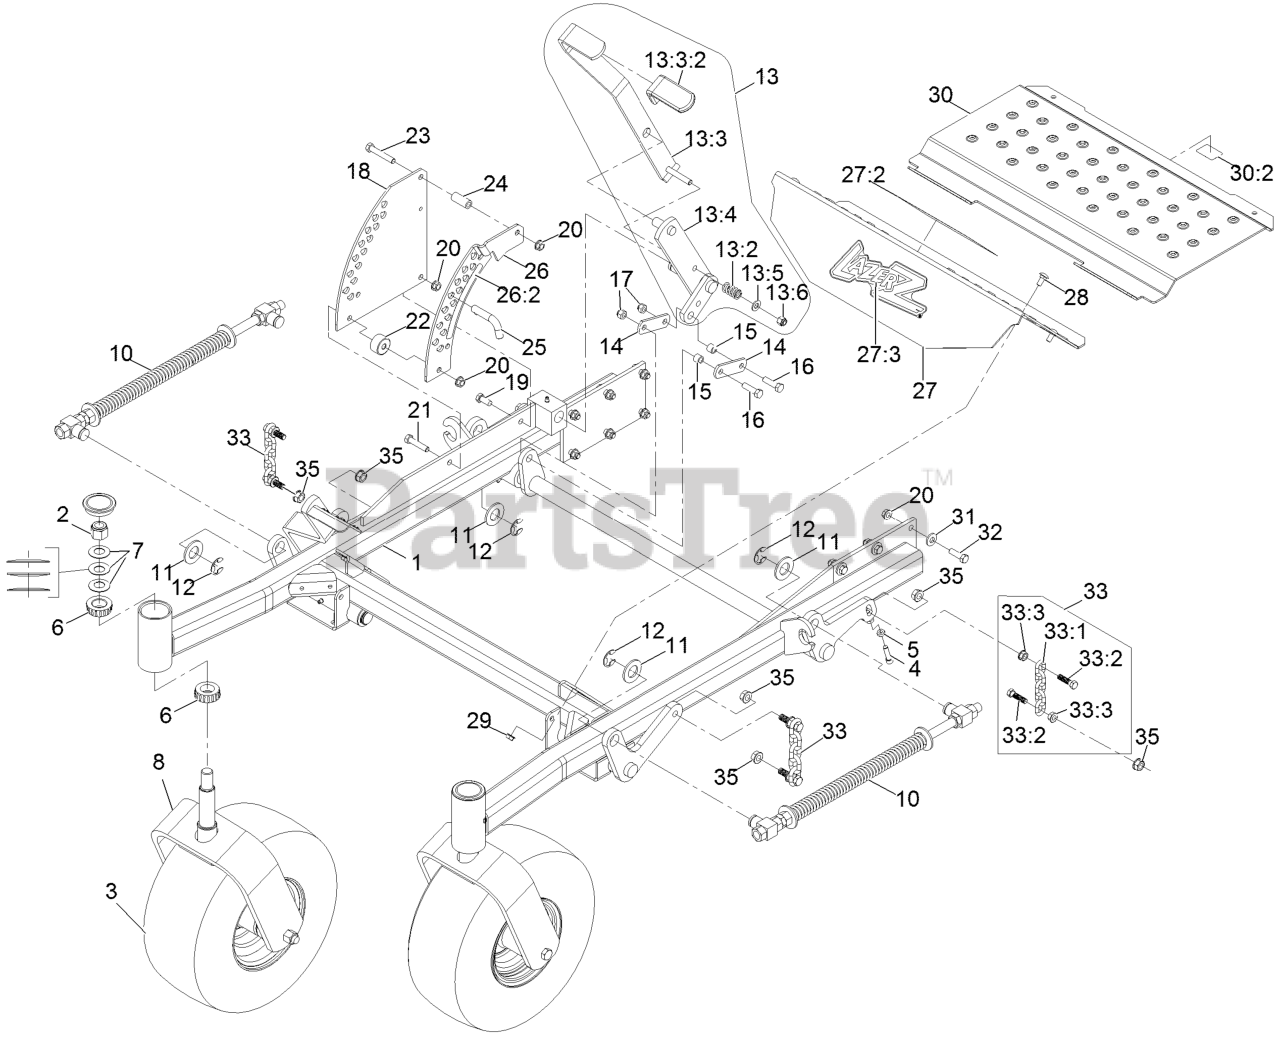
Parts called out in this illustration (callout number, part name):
1	ASM-FRT FRM 725
2	NUT-LOCK, NI
3	WHEEL & TIRE ASM
4	SCREW-HSH
5	NUT-JAM
6	Cone-Bearing Tapered Roller
7	WASHER-BELLVILLE
10	ASM,FRONT FRAME SPRING
11	WASHER-FLAT
12	RING-RETAINING, EXT
13	ASM,Deck Lift Handle
13:2	SPRING-COMPRESSION
13:3	LIFT LEVER/GRIP ASM
13:3:2	GRIP-LEVER, LIFT
13:4	WLD,ARM DECK LIFT
13:5	WASHER-FLAT
13:6	NUT-LOCK, NI
14	ARM-LIFT, DECK
15	BUSHING
16	SCREW-HH
17	NUT-LOCK, NI
18	PLATE-DECK LIFT NOTCHED O
19	SCREW-HH
20	NUT-HHF, WHIZ
21	SCREW-HH
22	Stop, Deck Height
23	SCREW-HH
24	BUSHING-LEVER, LIFT
25	PIN-HOC
26	PLATE-LIFT, DECK W/DECAL
26:2	DECAL-HEIGHT, DECK
27	ASM, FLOORPAN FRONT W/DEC
27:2	DECAL,LAZER MODEL
27:3	DECAL-SLOPE
28	BOLT-CARR
30	ASM, FLOORPAN LIFTOUT W/D
30:2	DECAL-GUARD
31	WASHER-BELLEVILLE
32	SCREW-HH
33	DECK CHAIN ASM
33:1	CHAIN-LIFT, DECK
33:2	SCREW-HH
